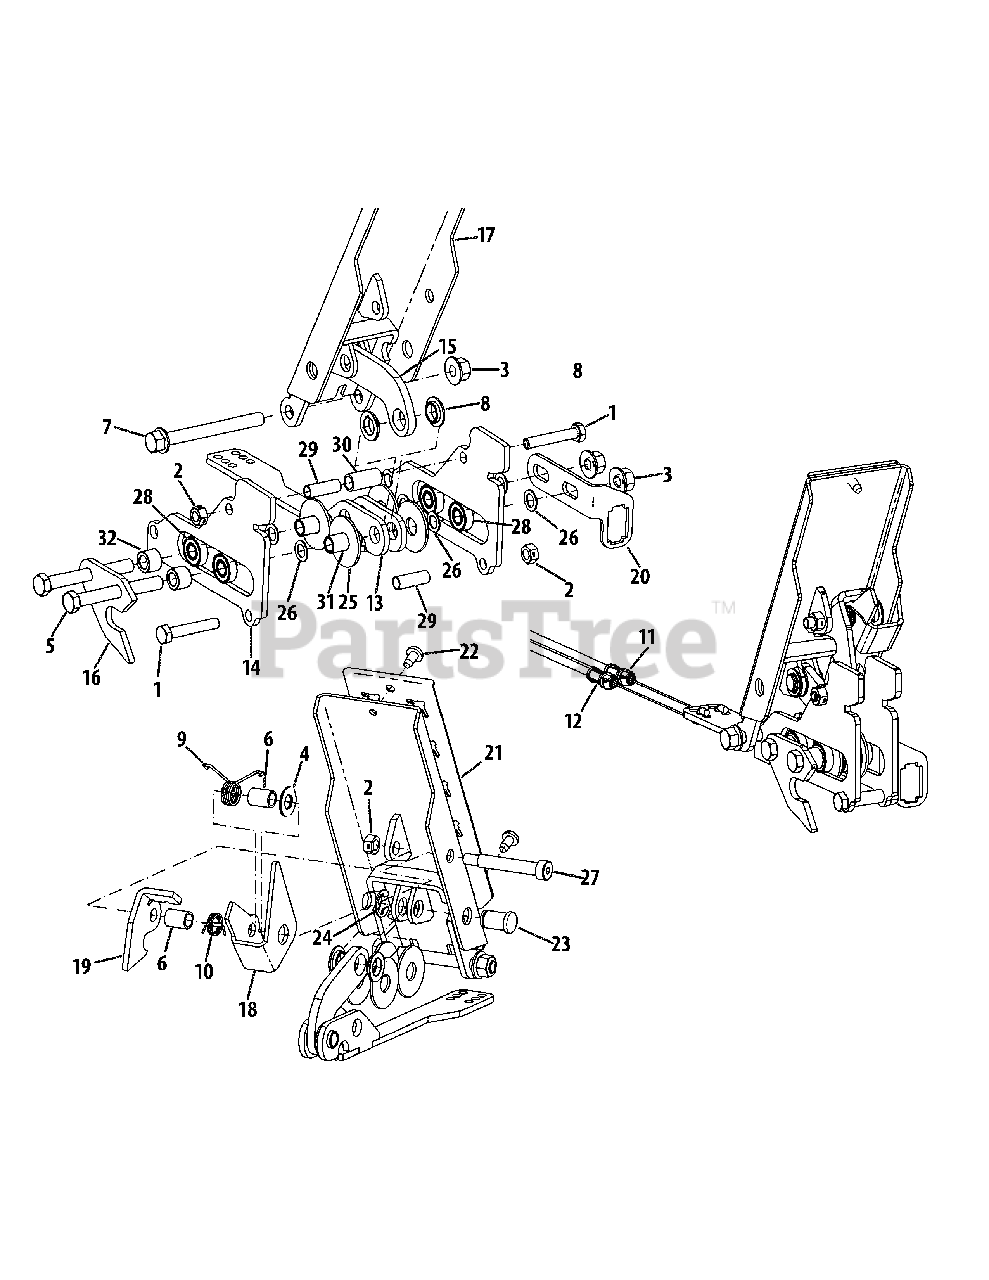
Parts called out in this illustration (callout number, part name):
1	Hex Screw, 5/16-18 x 1.75
2	Counter Lock Nut, 5/16-18
3	Flange Counter Lock Nut, 3/8-16
4	Washer, .416 x .875 x .046
5	Hex Screw, 3/8-16 x 3.00
6	Spacer, .380 x .500 x .667
7	Hex Screw, 3/8-16 x 3.50
8	Flange Bearing, .502 x .875 x .180
9	Torsion Spring
10	Torsion Spring
11	LH Brake Cable
12	RH Brake Cable
13	Brake Carrier Assembly
14	Brake Roller Guide Bracket
15	Brake Control Link
16	Lockout Plate
17	Brake Pedal Assembly
18	Park Engagement Bracket
19	Brake Hook Bracket
20	Brake Switch Mount Bracket
21	Brake Pedal Grip
22	Screw, 1/4-20 x .5
23	Pin, .500 x .804
25	Flat Washer, .531 x 1.5 x .08
26	Washer, .39 x .62 x .03
27	Shoulder Screw, 5/16-18 x .375 x 2.00
28	Bearing, .375 x .875
29	Spacer, .319 x .375 x 1.056
30	Spacer, .384 x .500 x 1.000
31	Spacer, .38 x .5 x .955
32	Spacer, .385 x .625 x .458
